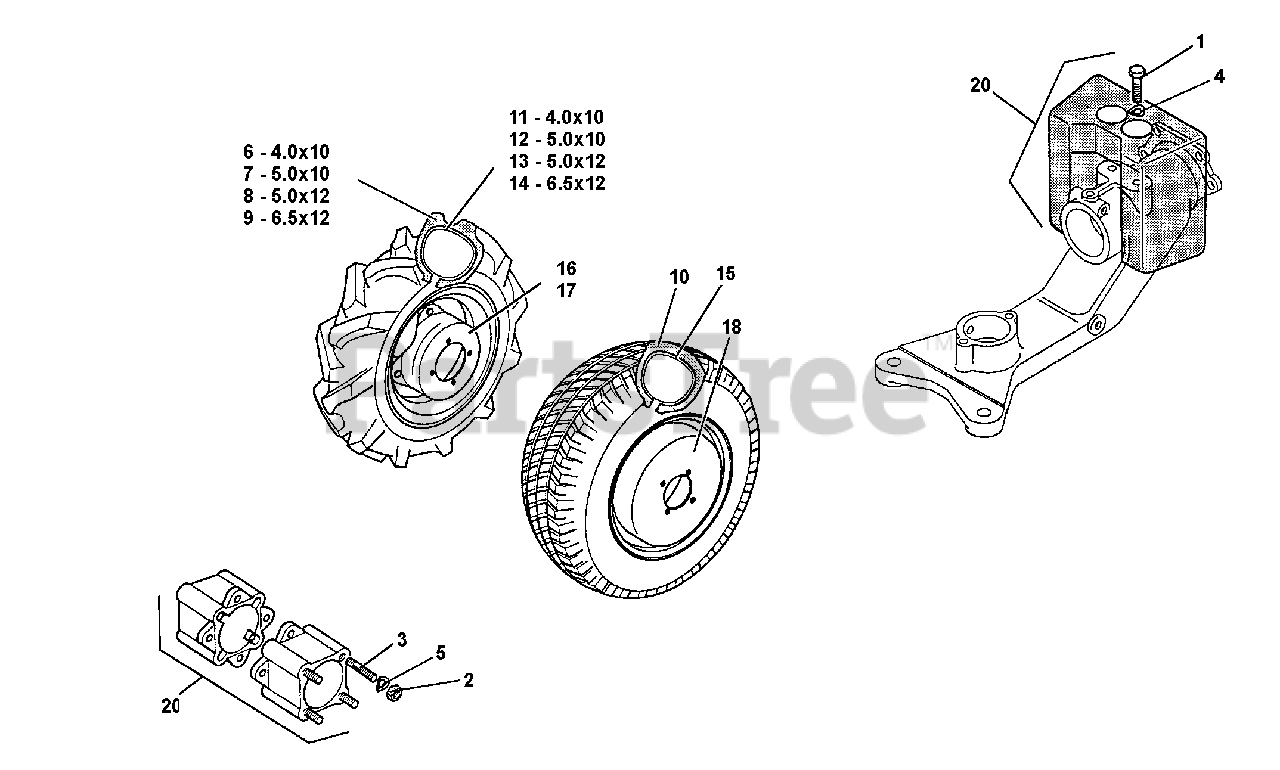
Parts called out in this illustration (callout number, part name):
1	SCREW, M8X25
3	STUD,M10X40X22X14
4	WASHER, M8.4
5	WASHER, LOCK, M10.5
6	TIRE, TRACTOR, 4.00X10
7	TIRE, TRACTOR, 5.00X10
8	TIRE, TRACTOR, 5.00X12
9	TIRE, TRACTOR, 6.50X12
10	TIRE, TURF, 20X8.00-10
11	TUBE, 4.00X10
12	TUBE, 5.00X10
13	TUBE, 5.00X12
14	TUBE, 6.50X12
15	TUBE, 20X8.00-10
16	RIM, 4.0X10 & 5.0X10
17	RIM, 5.00X12 & 6.5X12
19	WHEEL EXTENSIONS, 5" PAIR
20	CUTTER BAR WEIGHT, 26#
